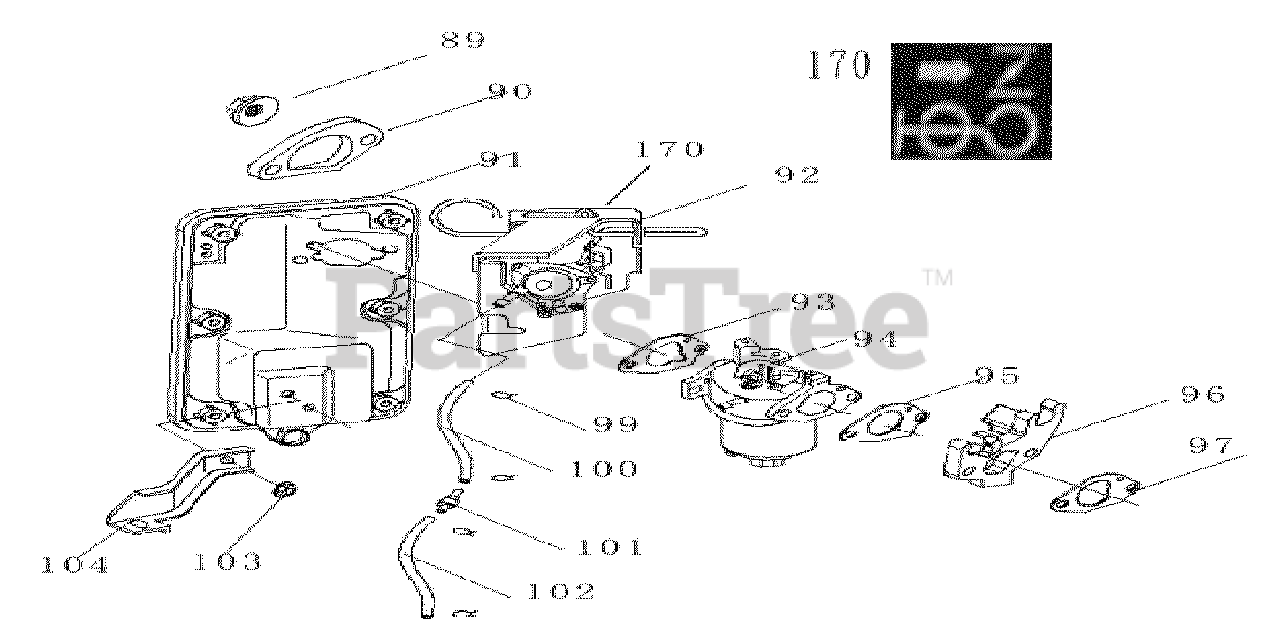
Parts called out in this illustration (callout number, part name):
89	M6 flanged nut
91	Air filter case
92	Choke air valve
94	Carburetor
99	Air pipe clip
100	Air pipe A
101	Unilateral valve
102	Air pipe B
103	M6 flanged nut
170	choke lever label
